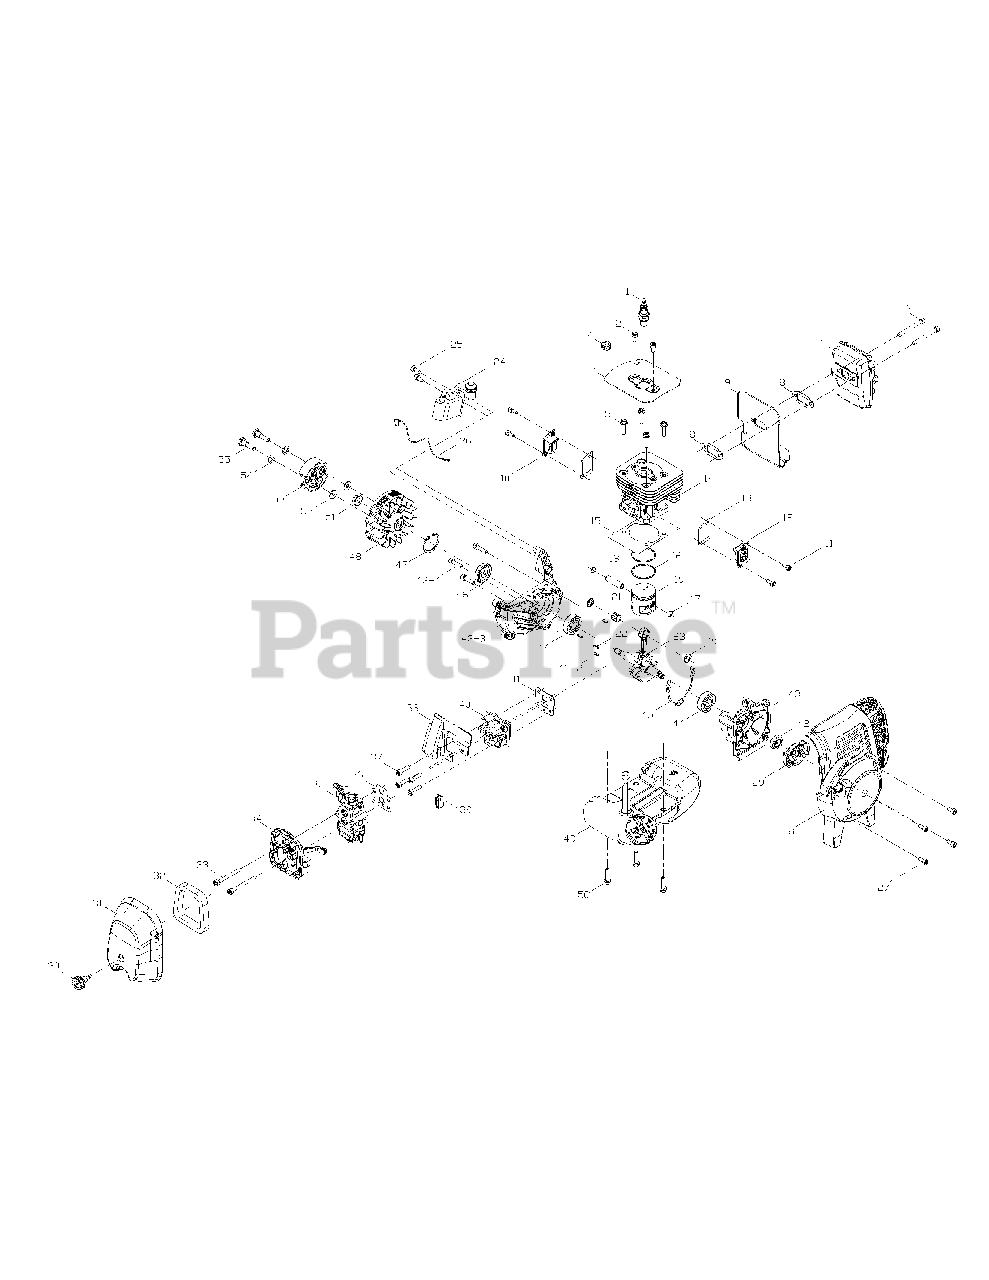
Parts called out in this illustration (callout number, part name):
1	SPARK PLUG
3	PLATE (SPARK SIDE)
7	MUFFLE ASS'Y
8	MUFFLE GASKET
9	MUFFLE PLATE
10	COVER (FLYWHEEL SIDE)
14	CYLINDER
16	PISTON RING
18	PISTON PIN
20	AXLS COVER
21	NEEDLE BEARING
23	CRANK/ROD ASS'Y
24	IGNITION COIL
26	COIL WIRE
28	STARTER HOUSING ASS'Y
29	PAWLS ASS'Y
30	KNOB
31	FILTER COVER
34	FILTER ASS'Y
35	CARBURETOR
36	CARBURETOR GASKET
40	INSULATOR
41	INSULATOR GASKET
43	CRANKCASE ASS'Y
43-1	CRANKCASE (STARTER SIDE)
43-3	CRANKCASE (FLYWHEEL SIDE)
47	C RING
49	FUEL TANK ASS'Y
51	NUT
53	CLUTCH (WITH SPRING)
54	WAVE PLATE
56	TRANSMISSION SUPPORT ASS'Y
63	BAG BEHIND
64	HANDLE ASS'Y
64-5	CENTERPLECE
64-6	PARTS BAG
66	BAG FRONT
67	STRINGHEAD ASS'Y
68	KNOB ASS'Y
69	COVER ASS'Y
69-1	PARTS BAG
69-4	KIT, KNIFE
70	HANDLE ASS'Y
70-2	HOUSING, HANDLE
70-3	WIRE ASS'Y, SWITCH
70-4	THROTTLE CABLE
70-8	LIBERATE SHAFT
70-10	LIBERATE CHUNK
70-13	HOUSING, HANDLE
71	NUT
